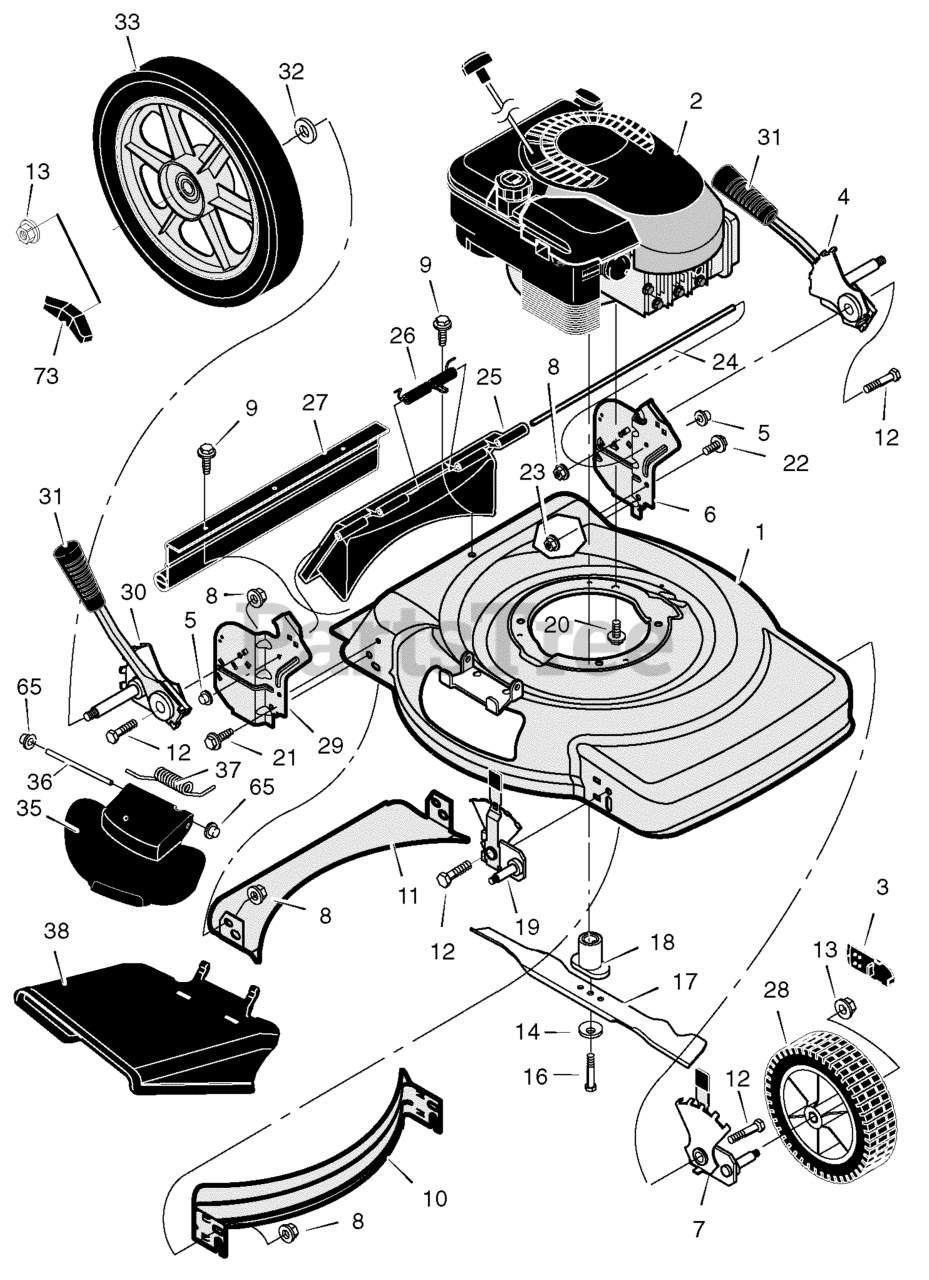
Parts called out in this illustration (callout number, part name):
1	Housing
2	Engine*
3	Cap, Hub (Optional)
4	Adjuster, Left Rear Height
5	Push On Cap
6	Bracket, Left Handle
7	Adjuster, Left Front Height
8	Nut, Flange
10	Baffle, Front
11	Baffle, Rear
13	Nut, Flange
14	Washer, Belleville
18	Adapter, Blade
19	Adjuster, Right Front Height
20	Bolt, Engine
21	Bolt
22	Bolt
23	Nut, Flange
24	Rod, Pivot
25	Door, Rear (Black)
26	Spring
27	Guard, Rear
28	Wheel & Tire
29	Bracket, Right Handle
30	Adjuster, Right Rear Height
33	Wheel, Rear
35	Cover, Mulch (Black)
36	Rod, Pivot
37	Spring, Torsion
38	Deflector, Chute (Black)
65	Push On Cap
73	Knob (Optional)
